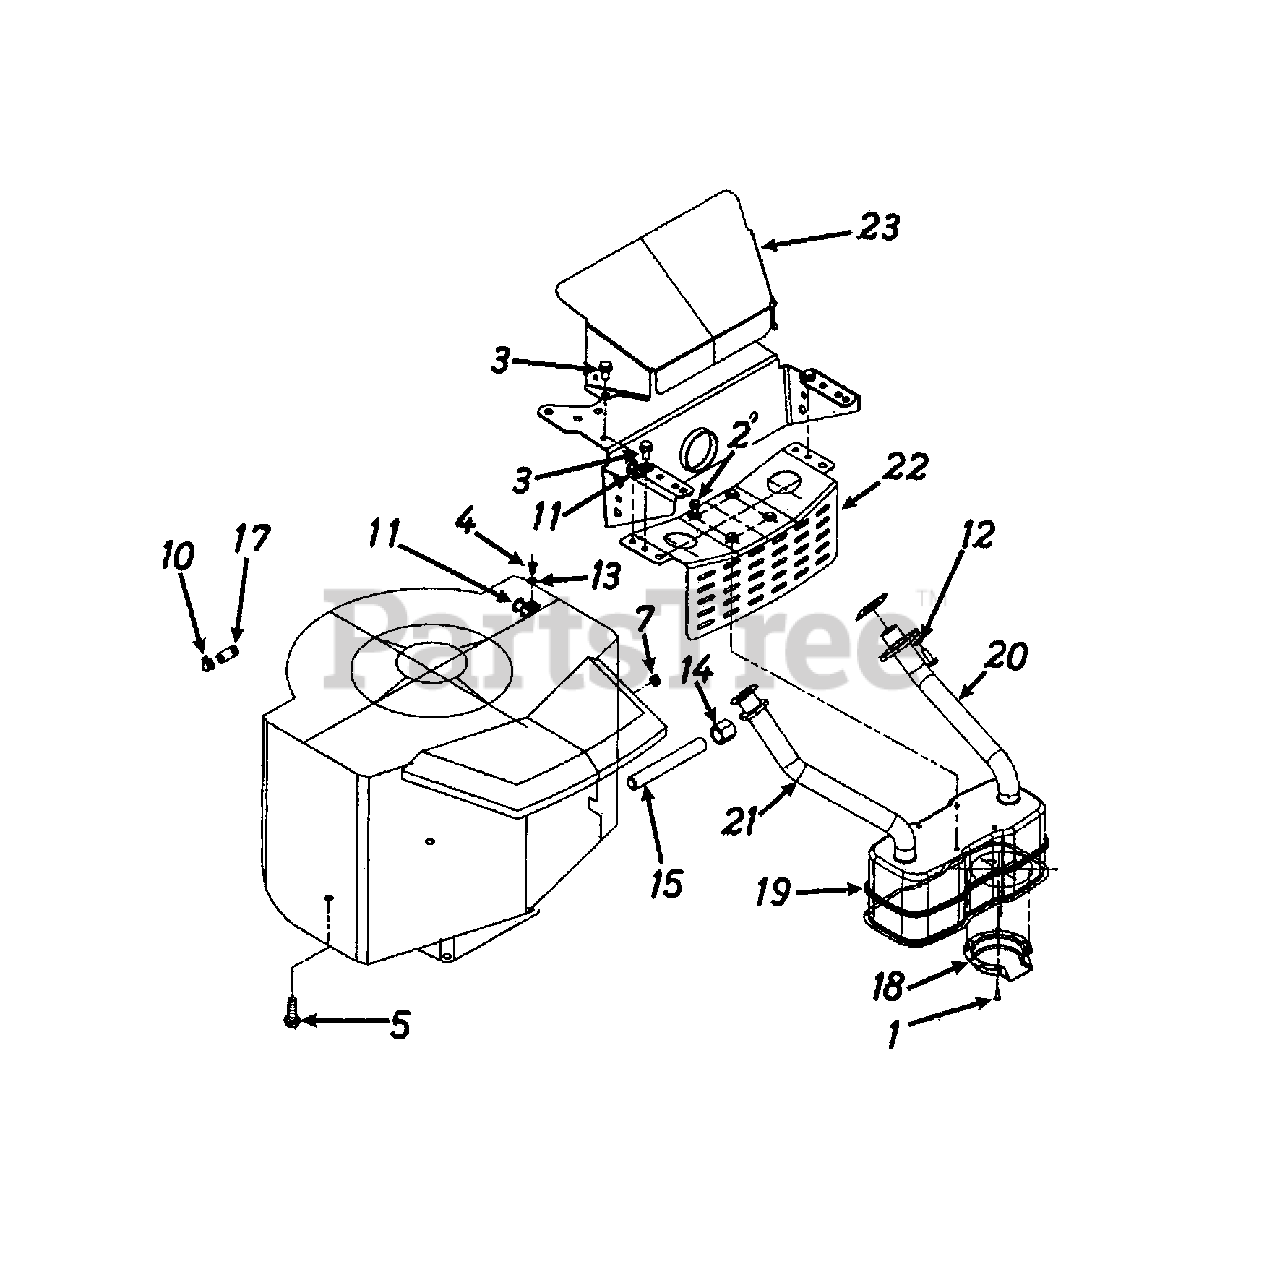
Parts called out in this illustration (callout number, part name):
1	Hex Tap Scr. #8-32 x .38" Lg.
2	Hex Wash. TT-Tap Scr. 1/4-20 x 5" Lg.
3	Hex Wash. TT-Tap Scr. 5/16-18 x .62" Lg.
4	Truss Mach. Scr. #10 x .5" Lg.
5	Hex Hd. Tap Scr. 3/8-16 x 1.25" Lg.
7	Hex Sems Nut 1/4-20 Thd.
10	Hose Clamp
11	Clamp
12	L-Wash. 1/4" I.D.
13	Fl-Wash. .188" I.D. x .438" O.D.
14	Oil Drain Cap
15	Pipe Nipple 3/8 x 18 NPT.
17	Fuel Line 26" Lg.
18	Deflector: Muffler
19	Muffler
20	Exhaust Pipe--L.H.
21	Exhaust Pipe--R.H.
